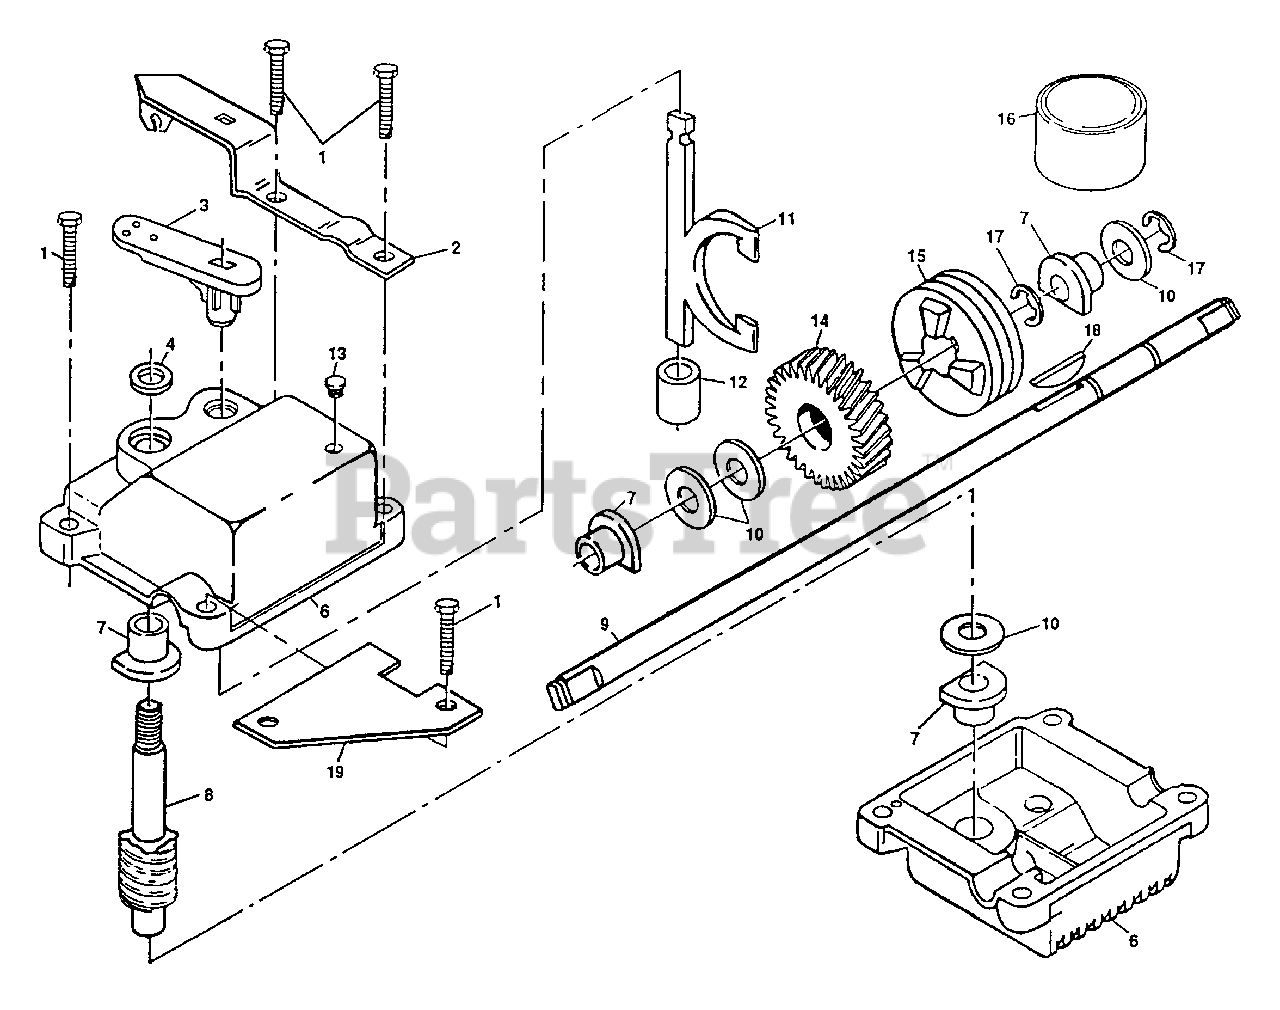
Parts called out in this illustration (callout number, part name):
1	Tapping Screw 1/4-20 x 1-1/4
2	Engagement Bracket
3	Shifter
4	Seal
6	Gear Case Halves Kit
7	Bearing
8	Worm Shaft
9	Drive Shaft
10	Hardened Washer
11	Clutch Yoke
12	Bushing
13	Plug
14	Helical Gear
15	Clutch Jaw
16	Grease (AYP part number)
17	E-Ring
18	Hi-Pro Key
19	Spring Bracket
